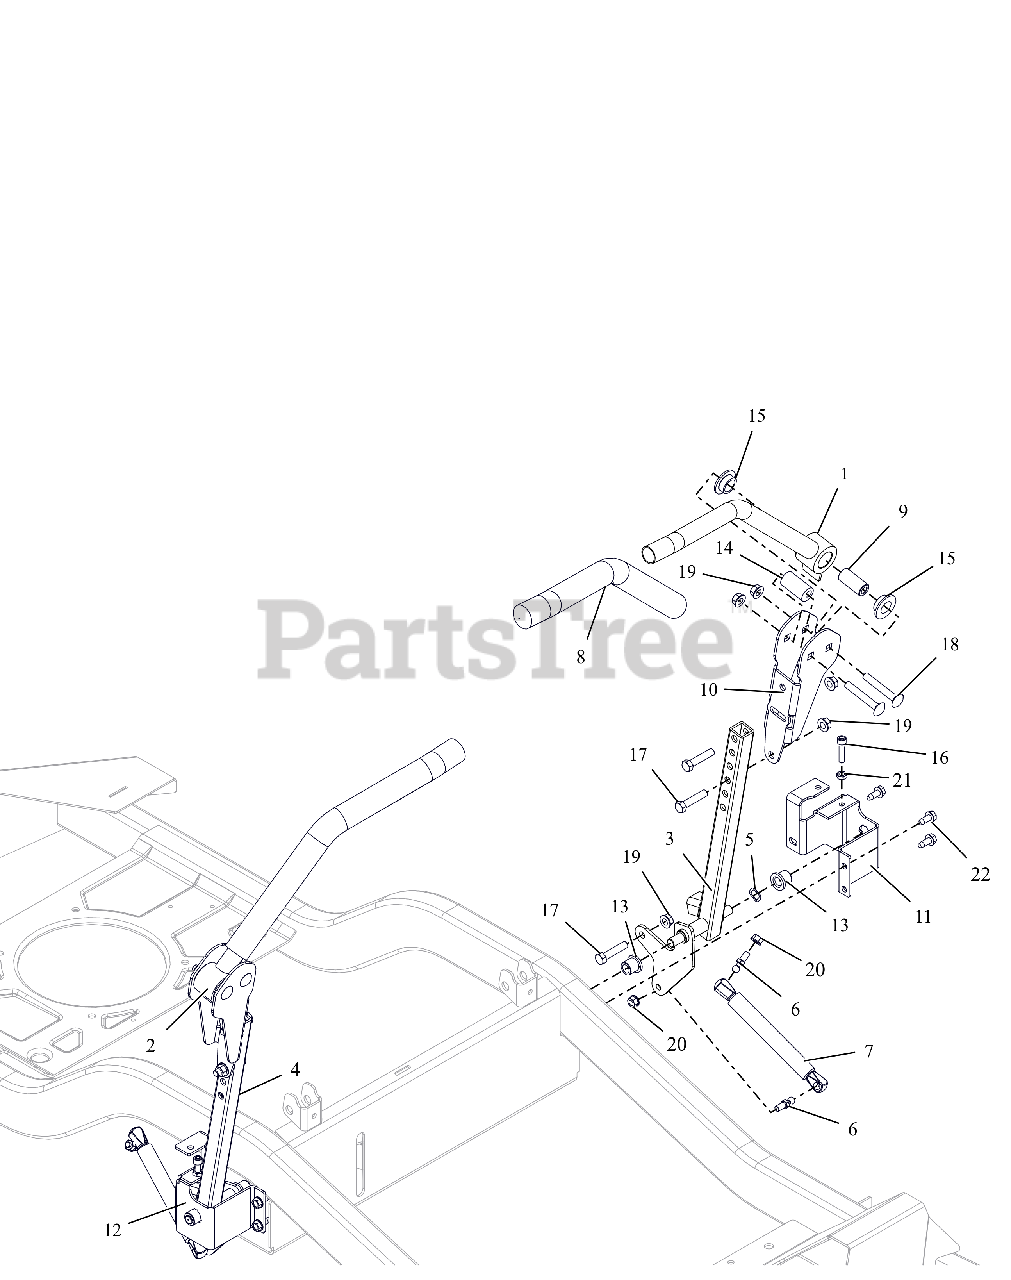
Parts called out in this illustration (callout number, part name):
1	WLDMT, CONTROL HANDLE- BLK
2	WLDMT, CONTROL HANDLE- BLK
3	WLDMT, STEERING LH
4	WLDMT, STEERING RH
5	WAVE WASHER .531X.781X.125FH
6	STUD- BALL
7	DAMPER
8	GRIP, HANDLEBAR
9	SPACER, STEERING ARM
10	ADJ UPPER CONTROL ARM BRKT-BLK
11	BRKT, STEERING ARM MOUNT -LH
12	BRKT, STEERING ARM MOUNT -RH
13	BHSG-FLG .500X.750X.750X.125
14	BSHG, ECCENTRIC.406X.875X1.625
15	BSHG-FLG .762X1.48X.44 NYL
16	SHCS .312-18 X 1.25 GR8 YWZC
17	BLT, HEX .38-16X1.75 G5 ZCC
18	BLT, RHSSN.38-16X2.50 G5 ZCC
19	NUT-LK-TOP-FLG .38-16 ZC120
20	NUT-LK-TOP-FLG .312-18 GF ZCC
21	NUT-JAM .312-18 G2 ZCC
22	SCR,TAP .312-18X.75 HWH TR ZCC
